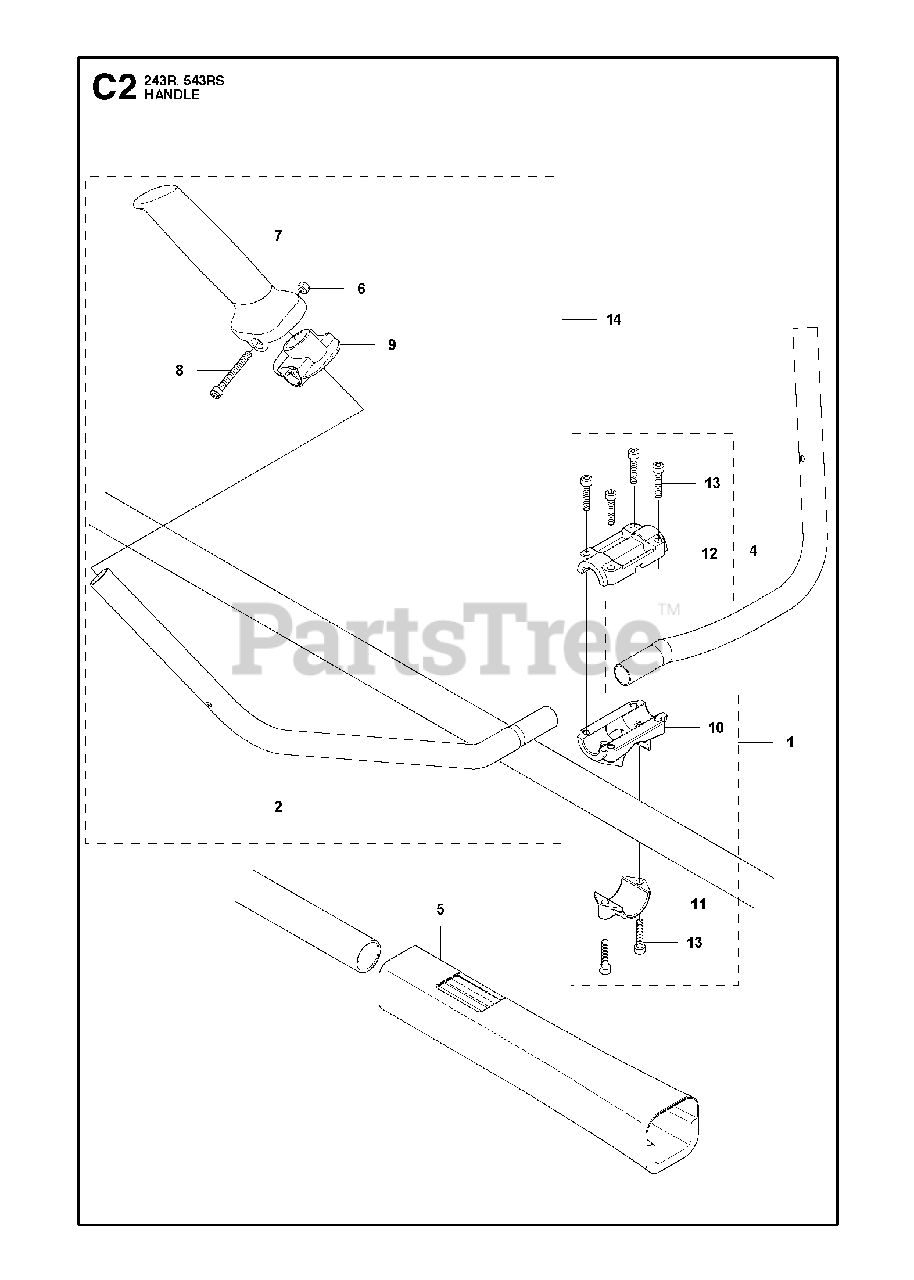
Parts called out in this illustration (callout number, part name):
1	HANDLE BRACKET ASSY 2
2	Left Handle
4	Handle, RH
5	PROTECTOR (RPLS 405017110)
6	NUT
7	HANDLE
8	Bolt
9	BRACKET
10	BRACKET Z354314112
11	CAPL Z354314121
12	CAP-U
13	BOLT TORX
14	Handle, LH
